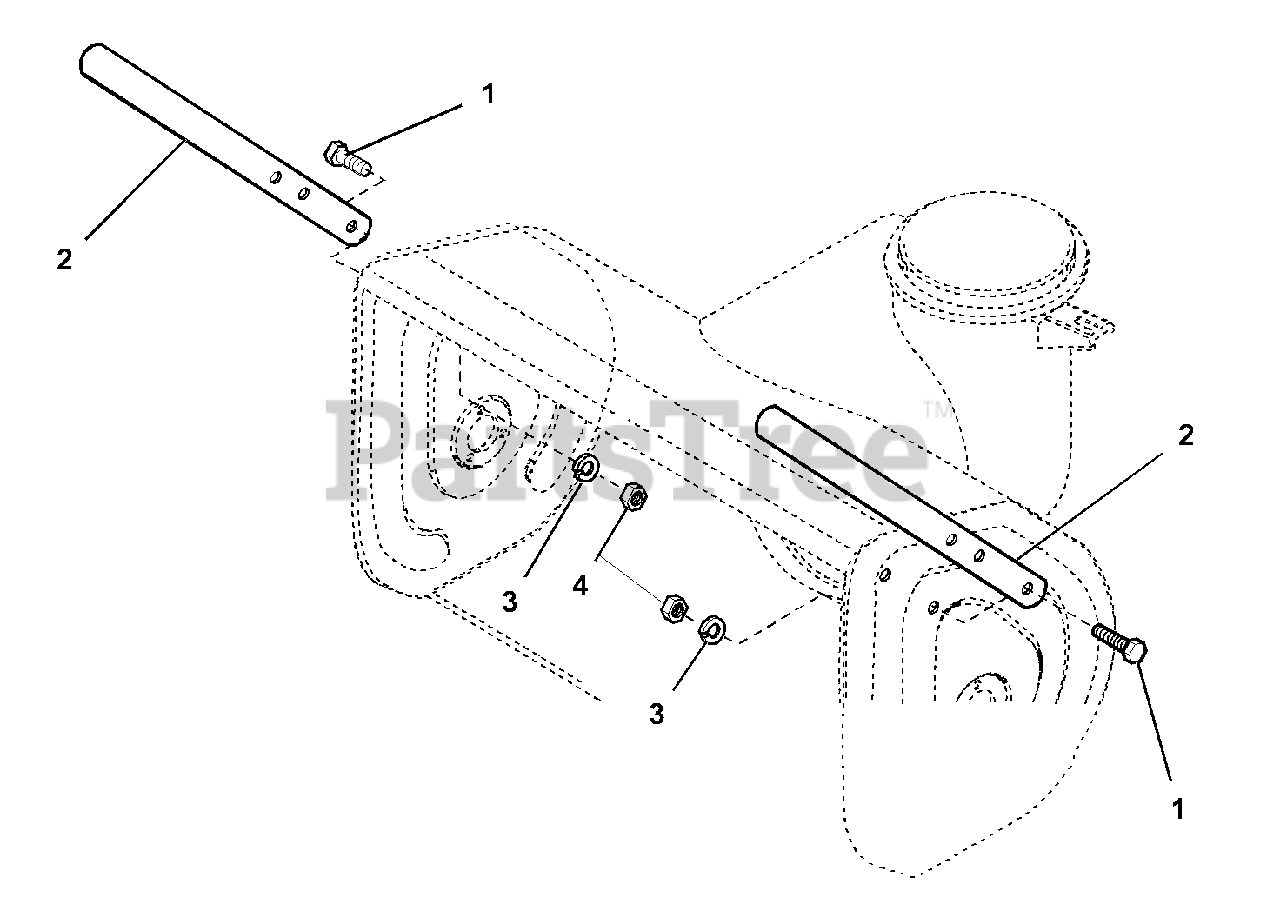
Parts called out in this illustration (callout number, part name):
1	CAPSCREW, Hex Hd., 5/16-18 x 3/4
2	CUTTER, Drift 20"
2	CUTTER, Drift 16"
3	LOCKWASHER, 5/16
4	NUT, Hex, 5/16-18
